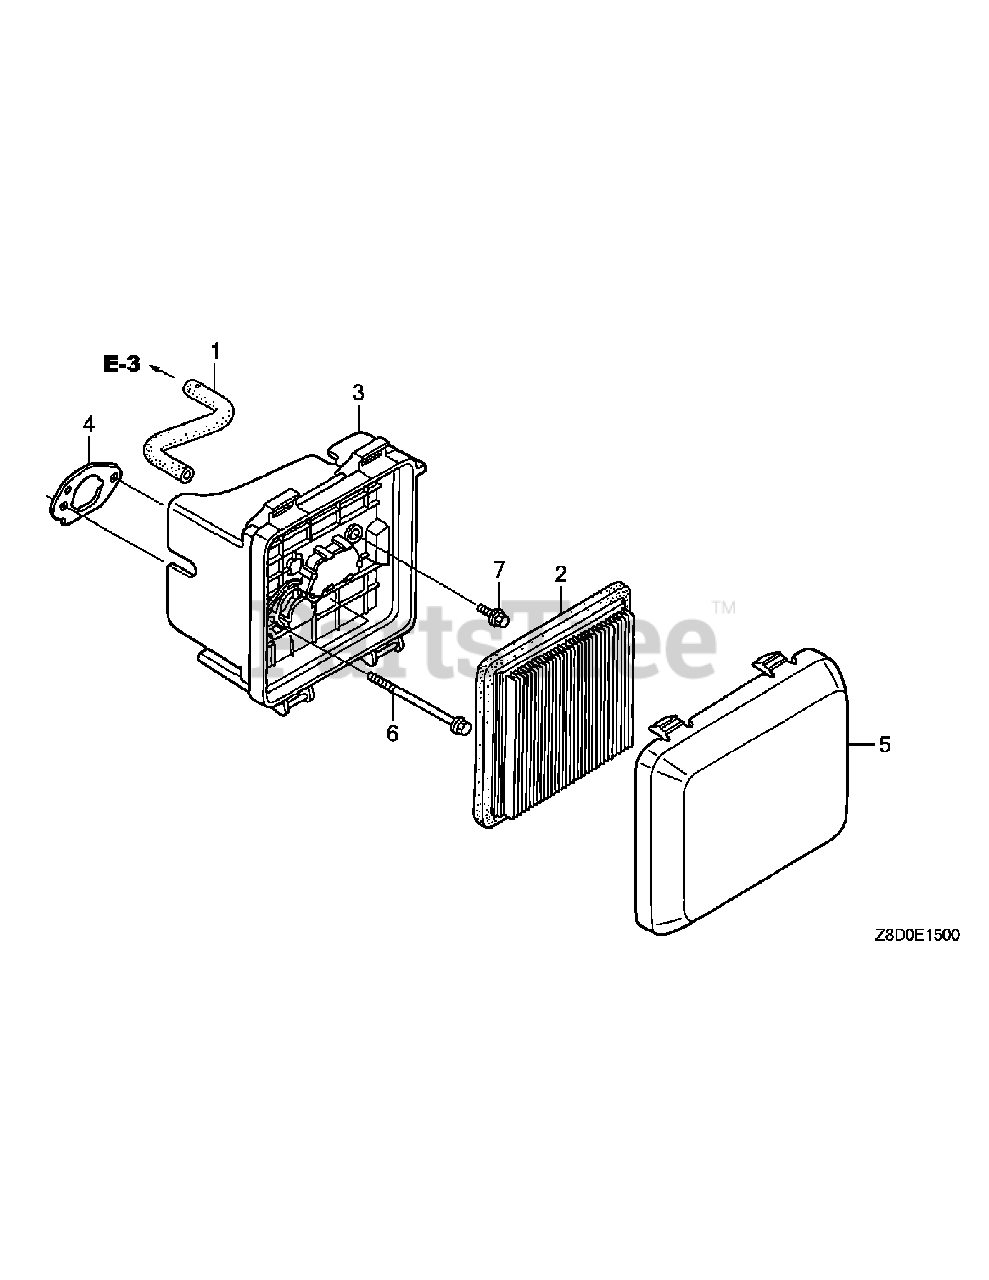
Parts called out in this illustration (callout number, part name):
1	Breather Tube
2	Air Cleaner Element
3	Air Cleaner Case Assembly
4	Air Cleaner Packing
5	Air Cleaner Cover
6	Flange Bolt, 6 x 86
7	Flange Bolt, 6 x 14
